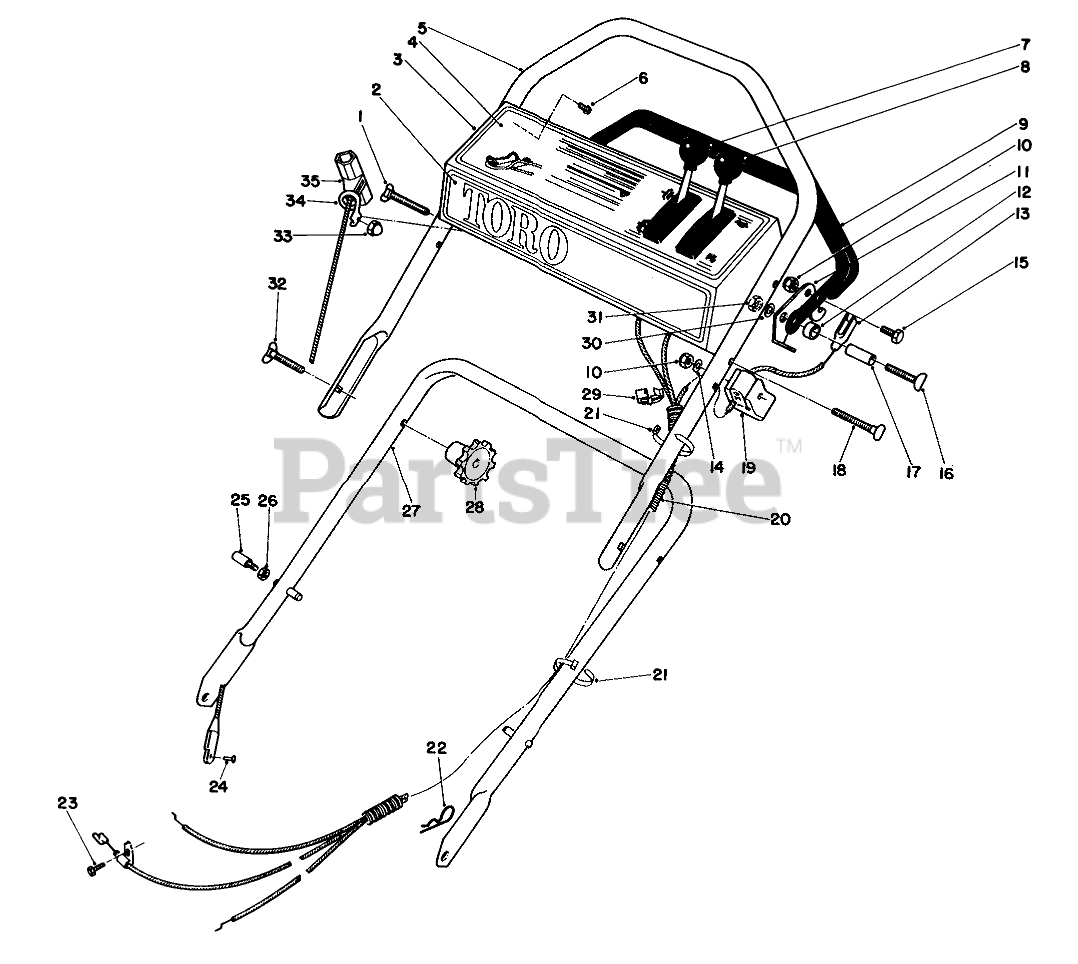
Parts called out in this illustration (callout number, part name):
1	HANDLE SCREW
2	Decal-Toro
3	Panel-Control (Incl. Ref. #4)
4	Decal-Instruction
5	UPPER HANDLE
6	SCREW-HWHTF
7	SERVICE TRACT. CONTROL
8	SERVICE THROTTLE CONTRO
9	Bar-Control
10	NUT-LOCK, NI
11	Lever-Control
12	Nylon Spacer
13	BRAKE CABLE
14	WASHER-FLAT
15	SCREW-HH
16	5/16-18 X 2 HNDLE SCREW
17	Spacer
18	SCREW-HANDLE
19	SUPPORT-CABLE
20	CONT. CABLE COVER
21	TIE-CABLE
22	PIN-COTTER, HAIR
23	SCREW-HH
25	Handle Pin
26	Nut
27	LOWER HANDLE ASSEMBLY
29	FITTING-RING
30	WASHER-FLAT
31	NUT-LOCK, NI
32	5/16-18 X 2 HNDLE SCREW
33	NUT-CAP
34	Guide
35	Rope-Starter
